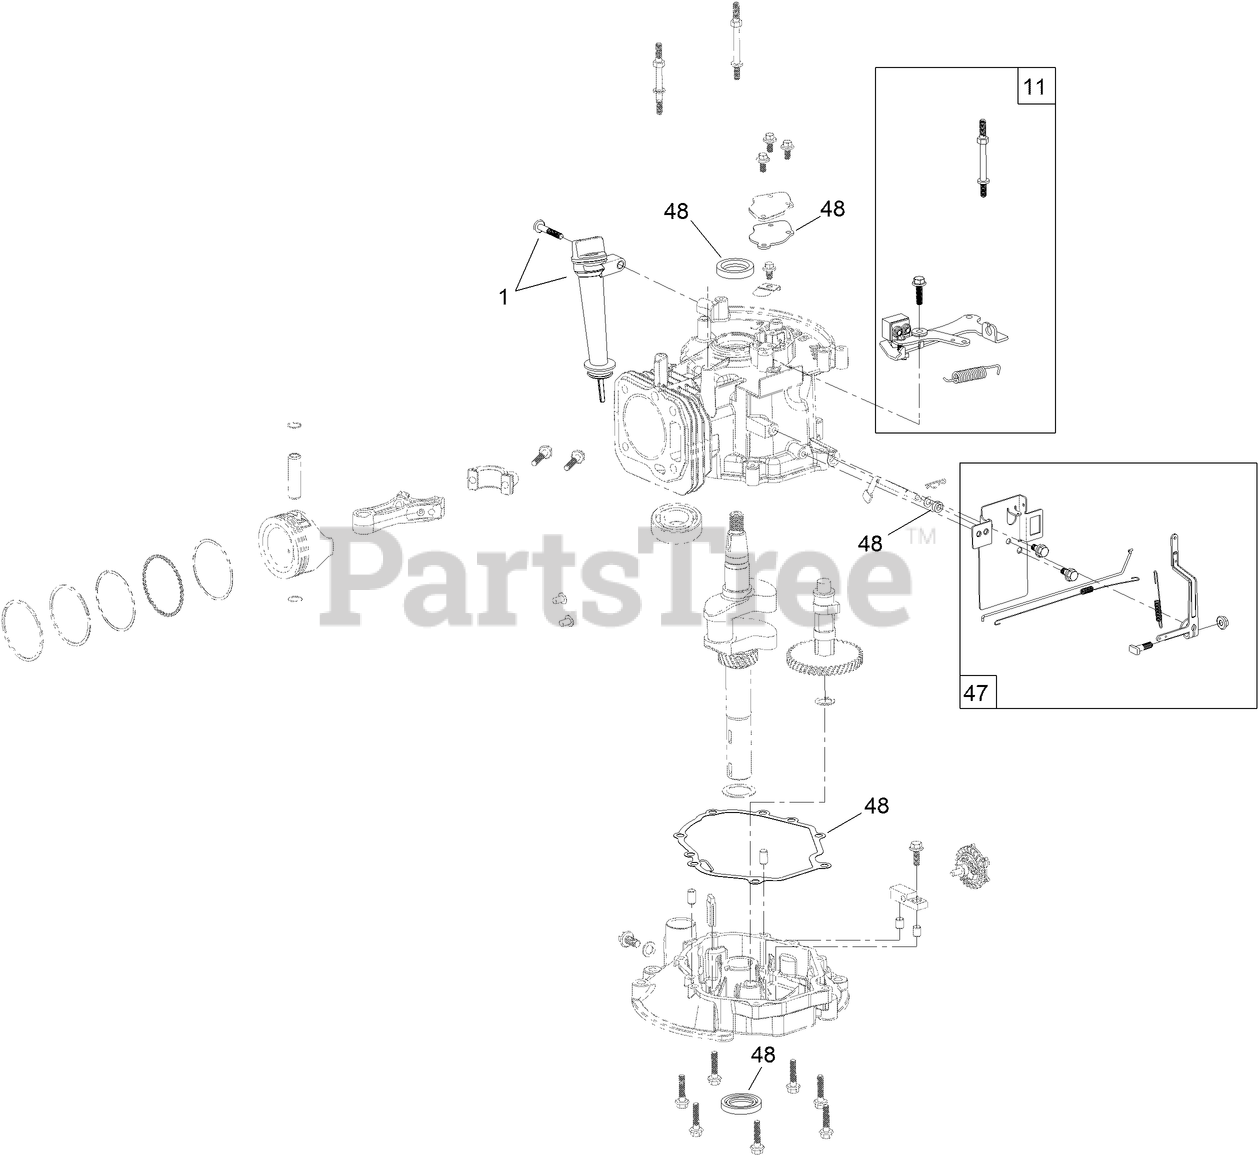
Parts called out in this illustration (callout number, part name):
1	DIPSTICK AND FILL TUBE KIT
11	BRAKE KIT
47	GOVERNOR ARM KIT
48	SEAL AND GASKET KIT
